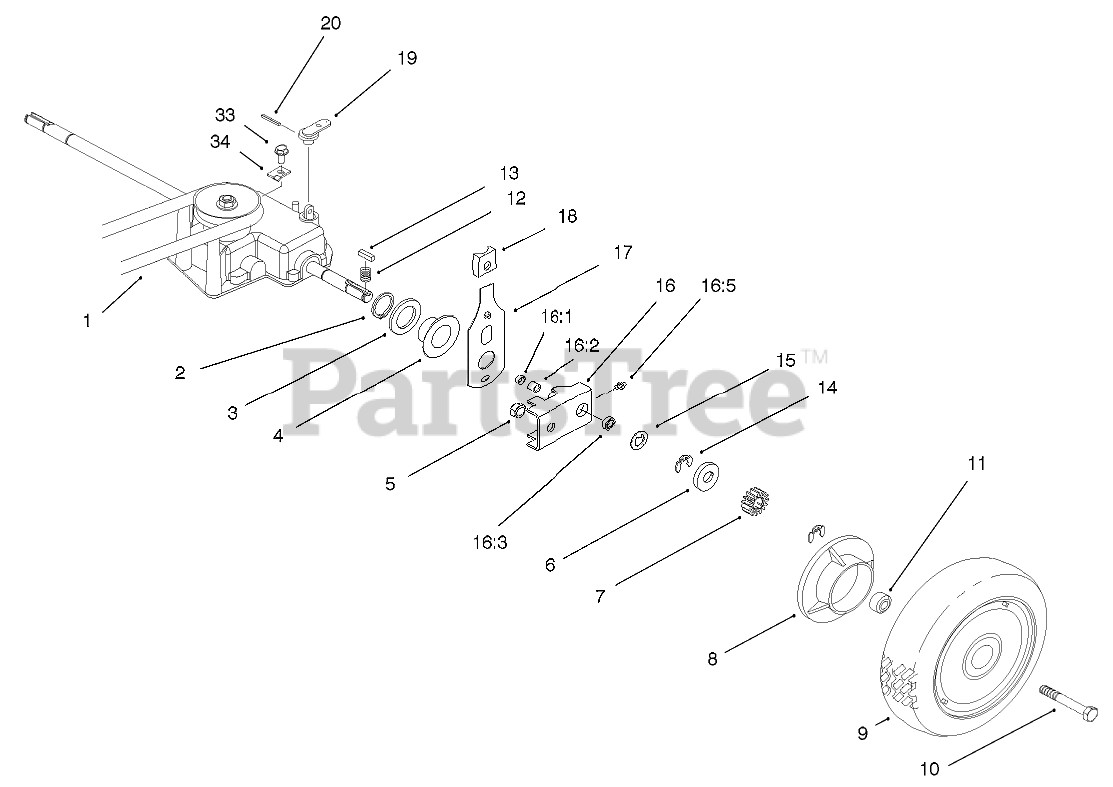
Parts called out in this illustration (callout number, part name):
1	V-BELT
2	RING-RETAINING
3	WASHER
4	CAP-END
5	NUT-LOCK, CONE
6	WASHER-THRUST, OUTER
7	GEAR-PINION
8	COVER-WHEEL
9	WHEEL AND TIRE ASM
10	SCREW-HH
11	SPACER-COVER, WHEEL
12	SPRING-COMPRESSION
14	RING-RETAINING
15	WASHER-THRUST, OUTER
16	PIVOT ARM ASM
16:1	SEAL-OIL
16:2	BEARING-ROLLER
16:3	BEARING-WHEEL
17	REAR SPRING ARM ASM
18	KNOB-ARM
19	LEVER-SHIFT
20	PIN-COIL
33	SCREW-HWHTF
34	CLAMP-CABLE
